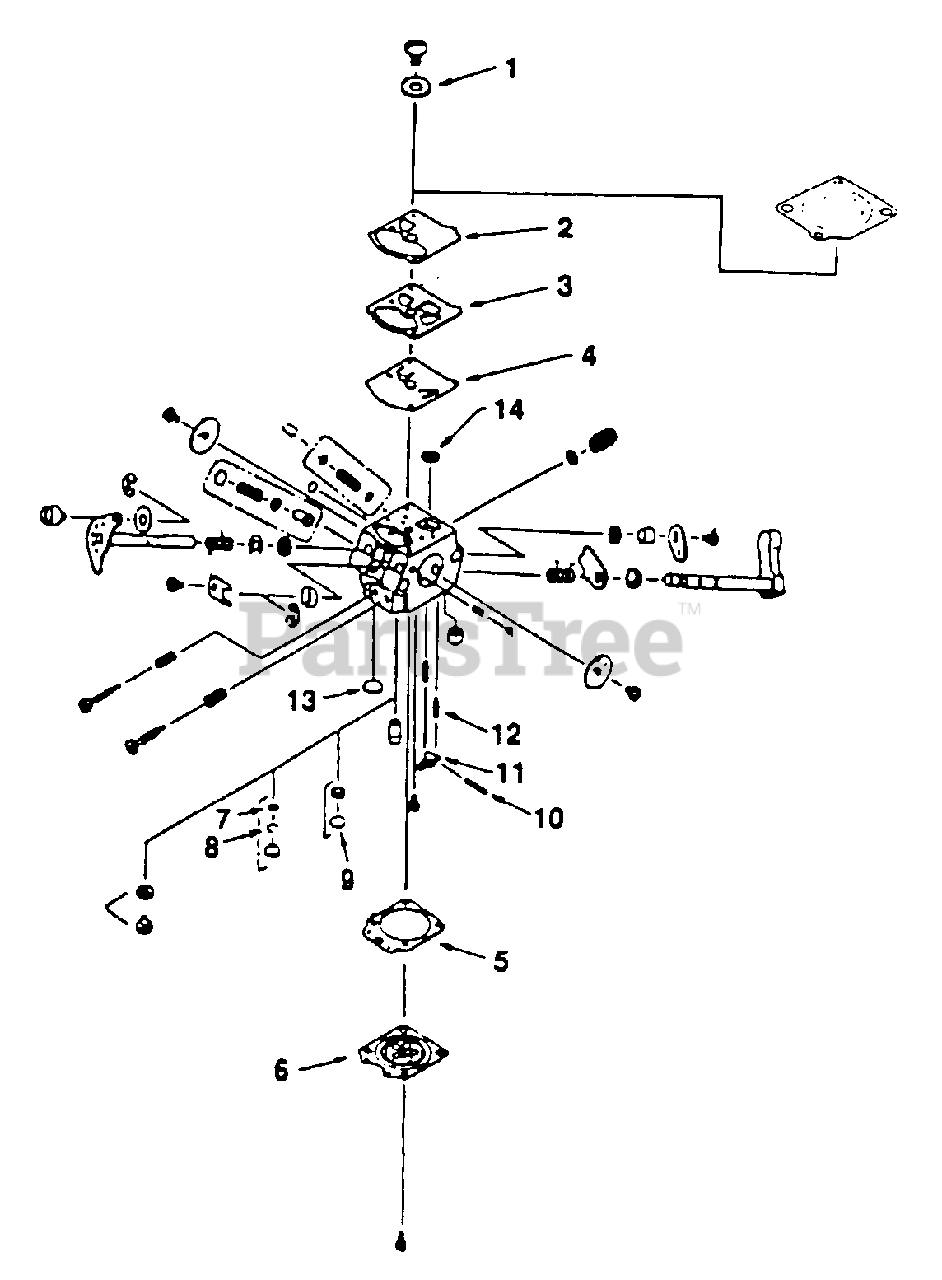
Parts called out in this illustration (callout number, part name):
1	Repair Kit
2	Gasket/Diaphragm KIt
2	Repair Kit
3	Gasket/Diaphragm KIt
3	Repair Kit
4	Gasket/Diaphragm KIt
4	Repair Kit
5	Gasket/Diaphragm KIt
5	Repair Kit
6	Gasket/Diaphragm KIt
6	Repair Kit
7	Repair Kit
8	Repair Kit
9	Repair Kit
10	Repair Kit
11	Repair Kit
12	Repair Kit
13	Repair Kit
14	Repair Kit
